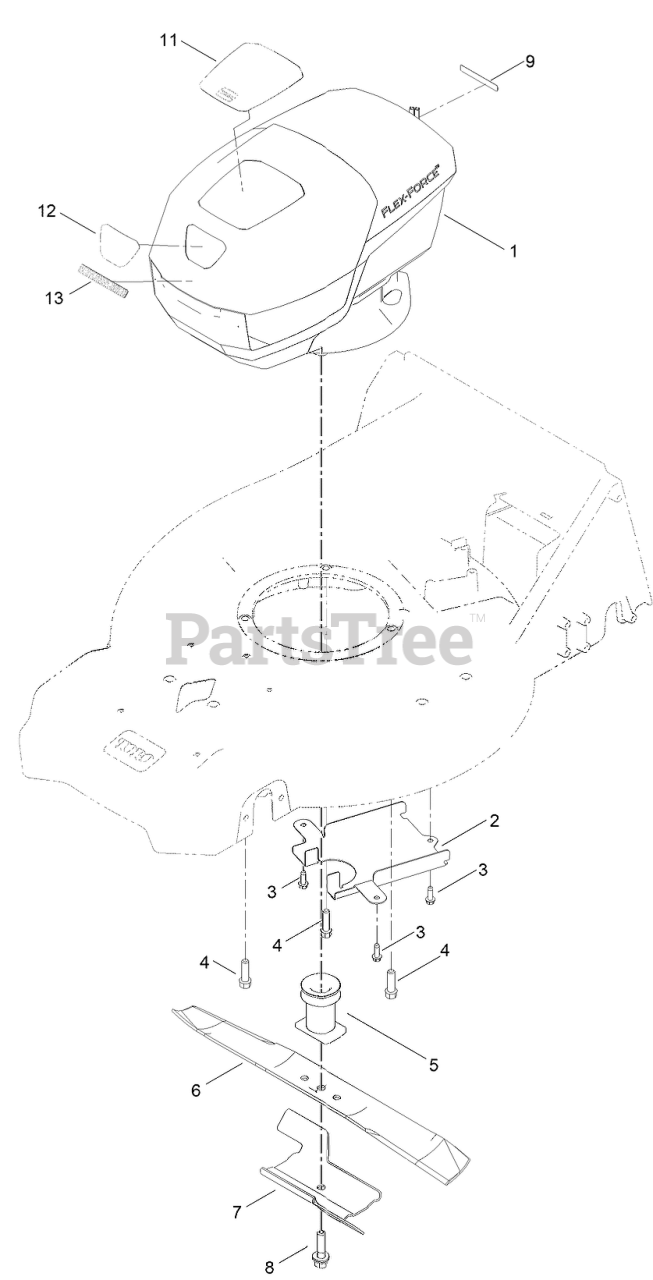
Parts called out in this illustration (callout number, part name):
1	MOTOR MODULE
2	COVER-BELT, BOTTOM
3	SCREW-HWHTF
4	SCREW-TAPTITE
5	DRIVER-BLADE
6	BLADE-21IN, RECYCLING
6	BLADE-21IN RECYCLING
7	ACCELERATOR-BLADE
8	BOLT-BLADE
9	DECAL-WARNING
